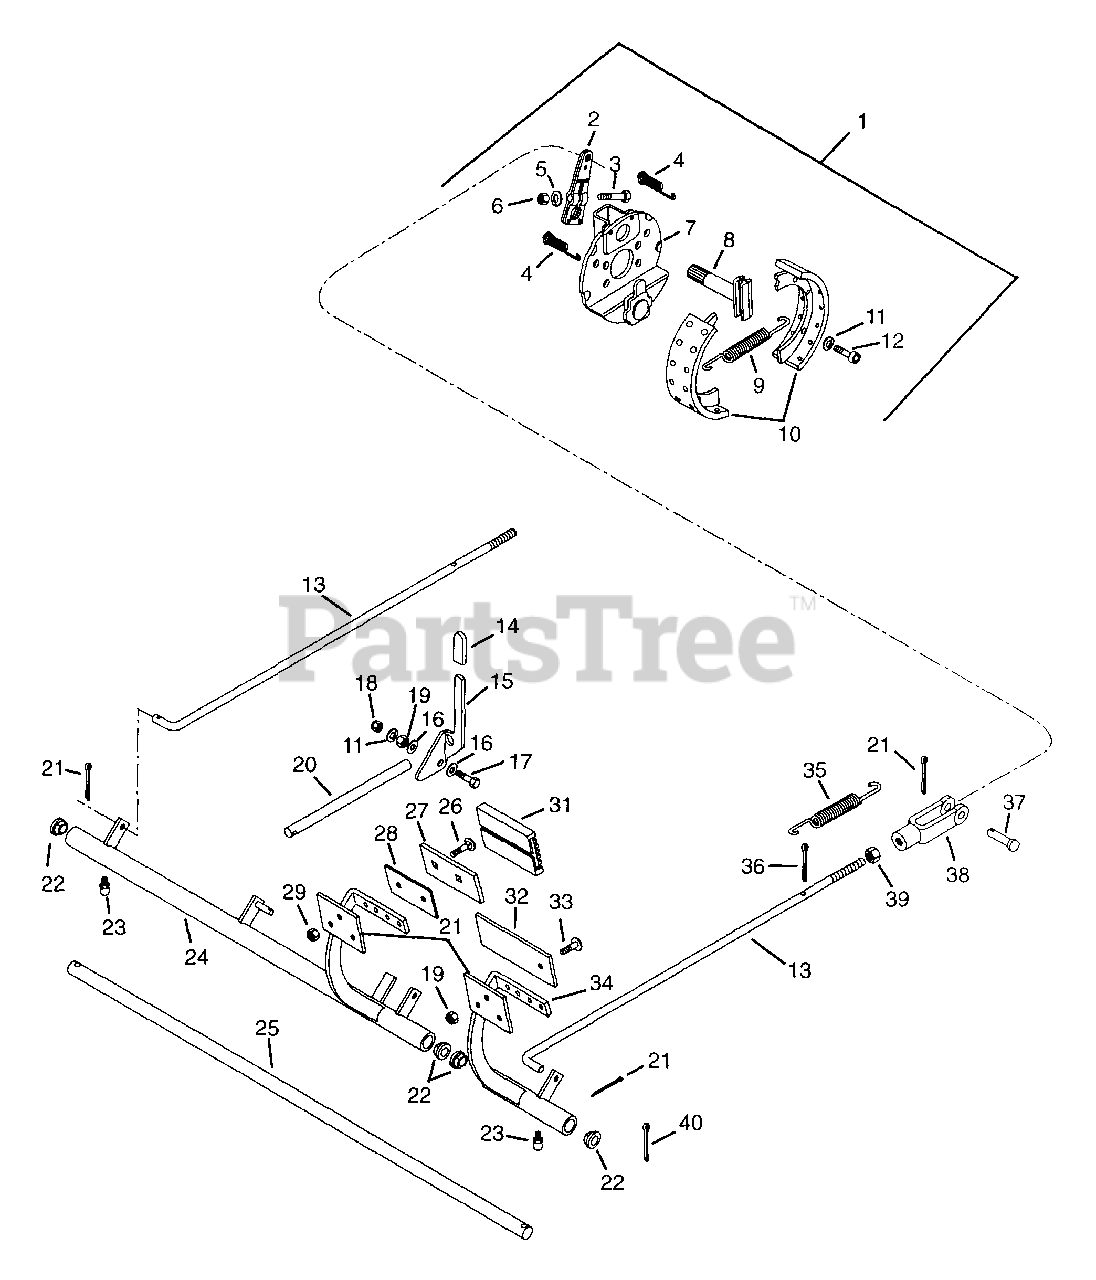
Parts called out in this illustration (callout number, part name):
1	Brake, 7 x 1.75 Mechanical
2	Arm, Cam Lever
3	Bolt-Hex .31-24 x 1.75
4	Spring, Shoe Ret Box
5	Washer-Lock .313 x .078
6	Nut-Hex .312-24 Grade 2
7	Plate, Brake
8	Cam, Brake
9	Spring, Shoe Return
10	Kit, Brake Shoe
11	Washer-Lock .375 x .094
12	Screw-Cap .38-16 x 1.25
13	Rod, Brake
14	Tip-Brake Lock Lever
15	Arm, Parking Brake Lock
16	Washer-Flat-Nylon .375 x .75 x .060
17	Bolt-Hex .38-16 x 1.38
18	Nut-Locking - Center .625-10 Grade 2
19	Nut-Hex .375-16 Grade 2
20	Rod, Brake Lock
21	Pin-Cotter .09 x .75
22	Bushing-Flange .630 x 1.000 x .625
23	Fitting-Lube .25-28 x .256
24	Weldment, Brake Pedal
25	Shaft, Brake
26	Bolt-Round Head Square Neck .25-20 x 1.25
27	Pedal, Brake
28	Plate, Brake
29	Nut-Locking-Nylon .250-20 Grade 2
30	Plate, Brake Lock Backing
31	Pad, Pedal
32	Arm, Brake Lock
33	Screw-Machine .25-20 x 1.00
34	Weldment, Brake Pedal
35	Spring-Tension .091 x .500 x 5.50
36	Pin-Cotter .12 x .75
37	Pin-Clevis .375 x .948
38	Clevis, .38-24 Adjustable
39	Nut-Jam .375-24
40	Pin-Cotter .12 x 1.25
